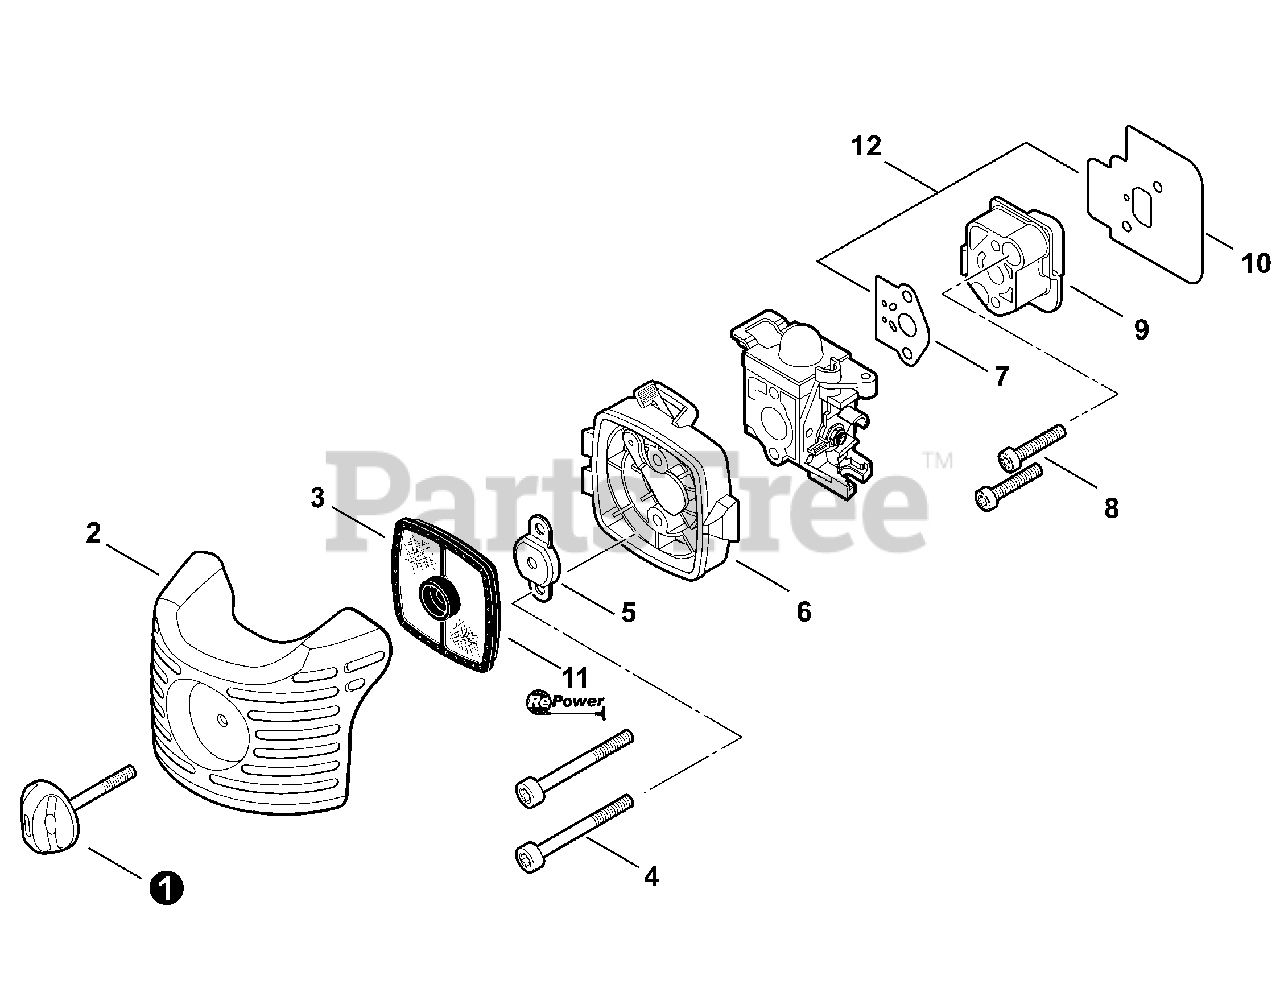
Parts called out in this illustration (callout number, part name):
1	THUMBSCREW
2	COVER, AIR FILTER
3	FILTER, AIR - DOUBLE LAYER
4	BOLT, TORX 5×65
5	PLATE, PREVENT
6	CASE ASSY, AIR FILTER
7	GASKET, INTAKE
8	BOLT, TORX 5×25
9	INSULATOR, INTAKE
10	HEAT SHIELD, INTAKE
11	TUNE-UP KIT - REPOWER
12	GASKET KIT
